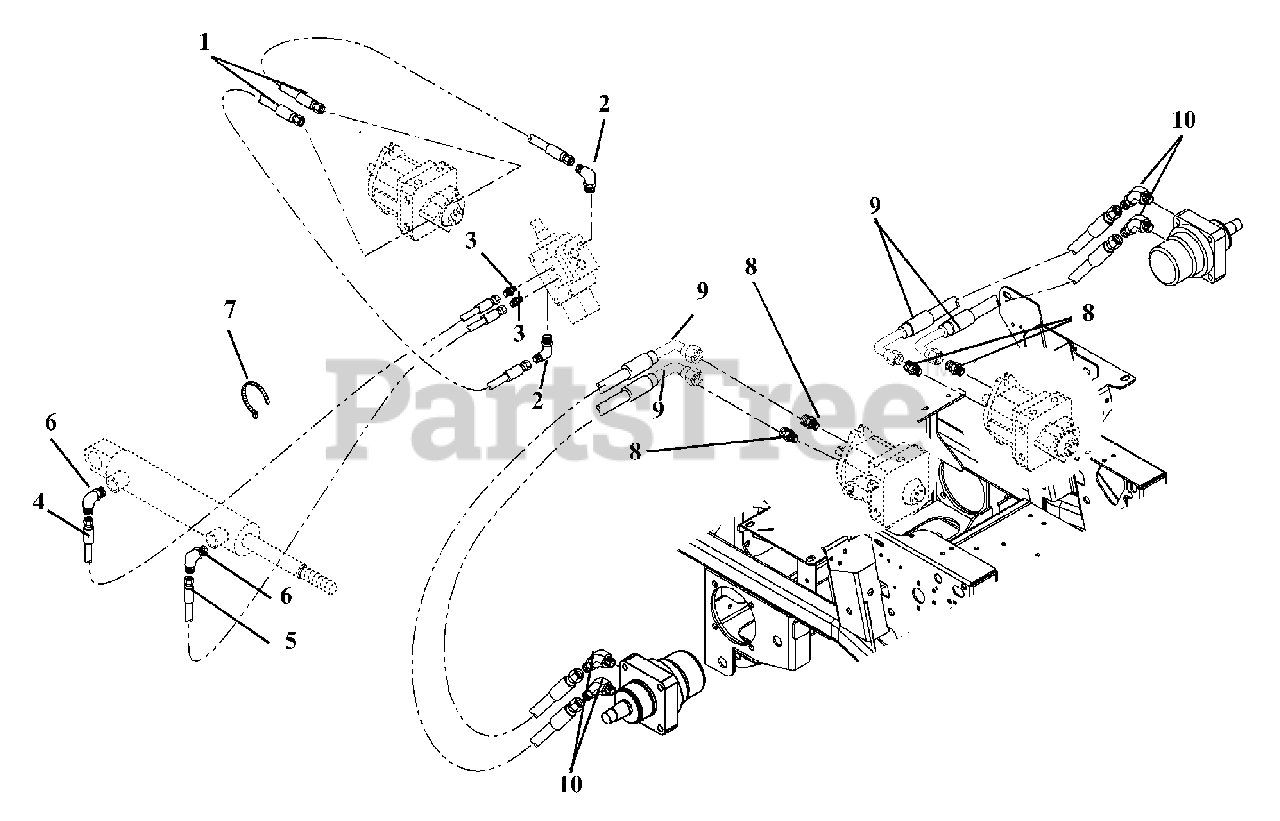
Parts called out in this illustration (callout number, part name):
1	HOSE,HYD.25-22-2K F04F9-F06FO
2	FTG, HYD ELBOW M6F-M8O
3	FITTING, HYD (4-6 F5OLO)
4	HOSE,HYD.25-42-2K F04F0-F04F4
5	HOSE,HYD .25-47-2K F04F0-F04F4
6	FITTING, HYD (4 C5OLO)
7	CABLE TIE LG 5-1/2
8	ADPTR,FACE SEAL 8X8 1/2 O-RING
9	HOSE,HYD .50-17-2K F08F0-F08F9
10	FITTING, HYD (8-10 V5OLO)
